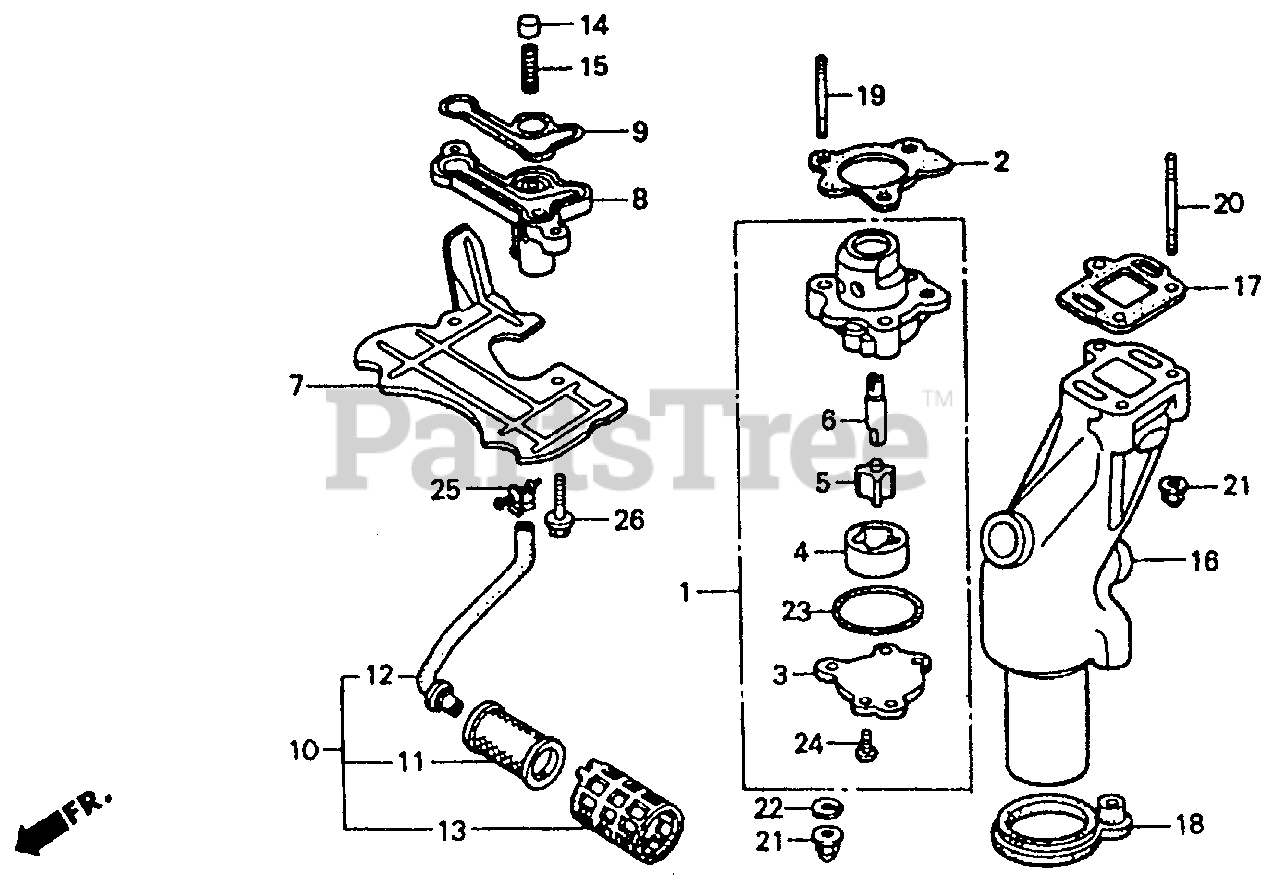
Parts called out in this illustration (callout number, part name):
1	PUMP ASSY., OIL
2	GASKET, PUMP BODY
3	COVER, OIL PUMP
4	ROTOR, OIL PUMP (OUTER)
5	ROTOR, OIL PUMP (INNER)
6	SHAFT, OIL PUMP
7	PLATE, GUARD
8	FLANGE, OIL FILTER
9	GASKET, OIL FILTER
10	FILTER ASSY., OIL
11	FILTER, OIL
13	HOLDER, OIL FILTER
14	VALVE, CHECK
15	SPRING, VALVE
16	PIPE, EX. *TBLACK* (BLACK)
17	GASKET, EX. PIPE
18	GROMMET, WATER TUBE
19	BOLT, STUD (6X39)
20	BOLT, STUD (6X42)
21	NUT, CAP (6MM)
22	WASHER, SPRING (6MM)
23	O-RING, PUMP COVER
24	SCREW, PAN (5X8)
25	CLIP, TUBE (A12)
26	BOLT, FLANGE (6X22)
